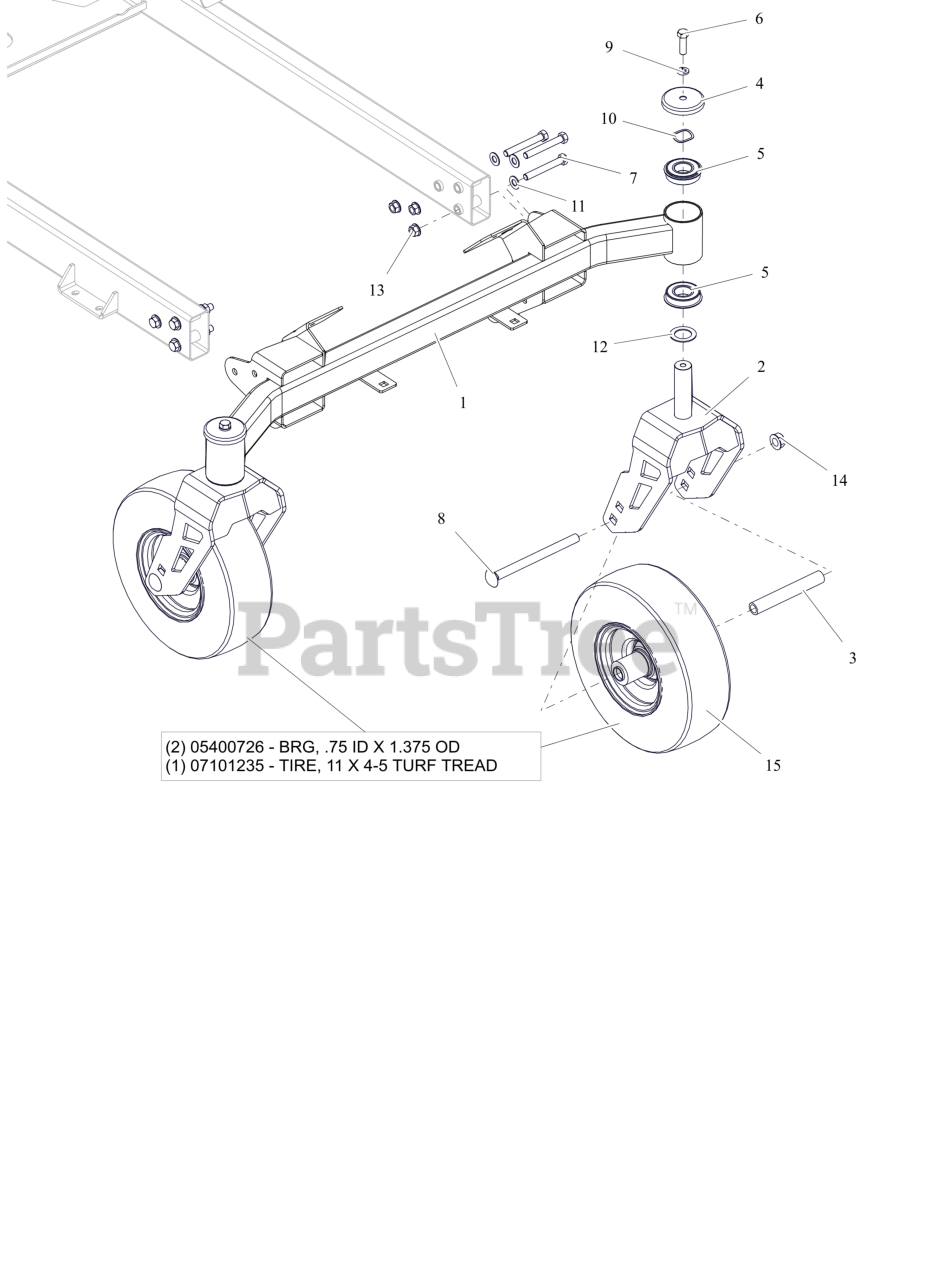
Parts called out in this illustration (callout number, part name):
1	WMT-FRONT AXLE-X/XL
2	WLDMT, CASTER FORK-XD (ORANGE)
3	SPACER, ROLLED WHEEL
4	SHIELD, AXLE BEARING
5	BEARING, BALL -2.000 OD X 1.000 ID X .5625 W/RING
6	BLT, HEX .38-16X1.25 G5 ZCC
7	BLT, HEX .38-16X2.75 G8 ZCC
8	BLT, RHSN .50-13X6.50 G5 ZCC
9	WSHR,LK-REG .375X.094 ZCC
10	WSHR-WAVE 1.0X1.25X.028 .145FH
11	WSHR,FLT-HRD.406X.812X.055 MZC
12	WSHR-HRD-THRS 1.007X1.542X.062
13	NUT-LK-TOP-FLG .375-16 GG ZCC
14	NUT-LK-TOP-FLG .500-13 GF ZCC
15	ASM, WHL/TIRE 11X4.00-5
15	BRG, .75 ID X 1.375 OD
15	LAWN TIRE FRONT, 11/4-5 TURF TREAD
